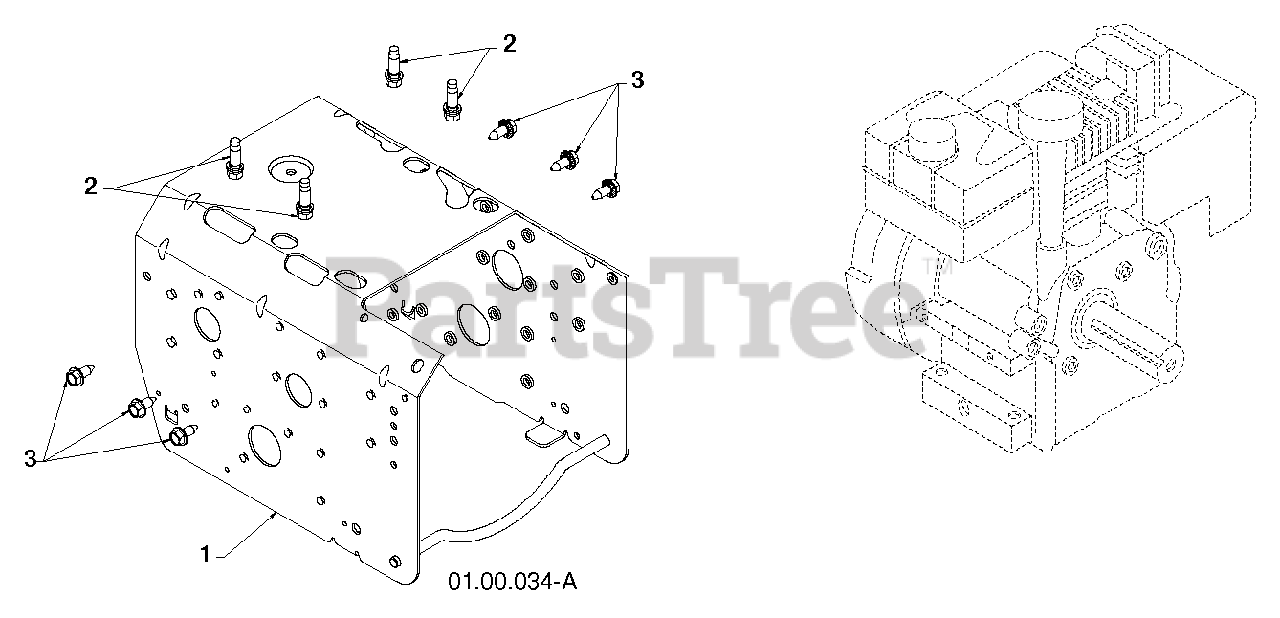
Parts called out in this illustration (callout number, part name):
1	FRAME.WELD.CHAIN.PNT.YELLOW
2	BOLT 3/8-16X1-1/8
3	BOLT.HEX.HD.WASHER.5/16-18X.75
